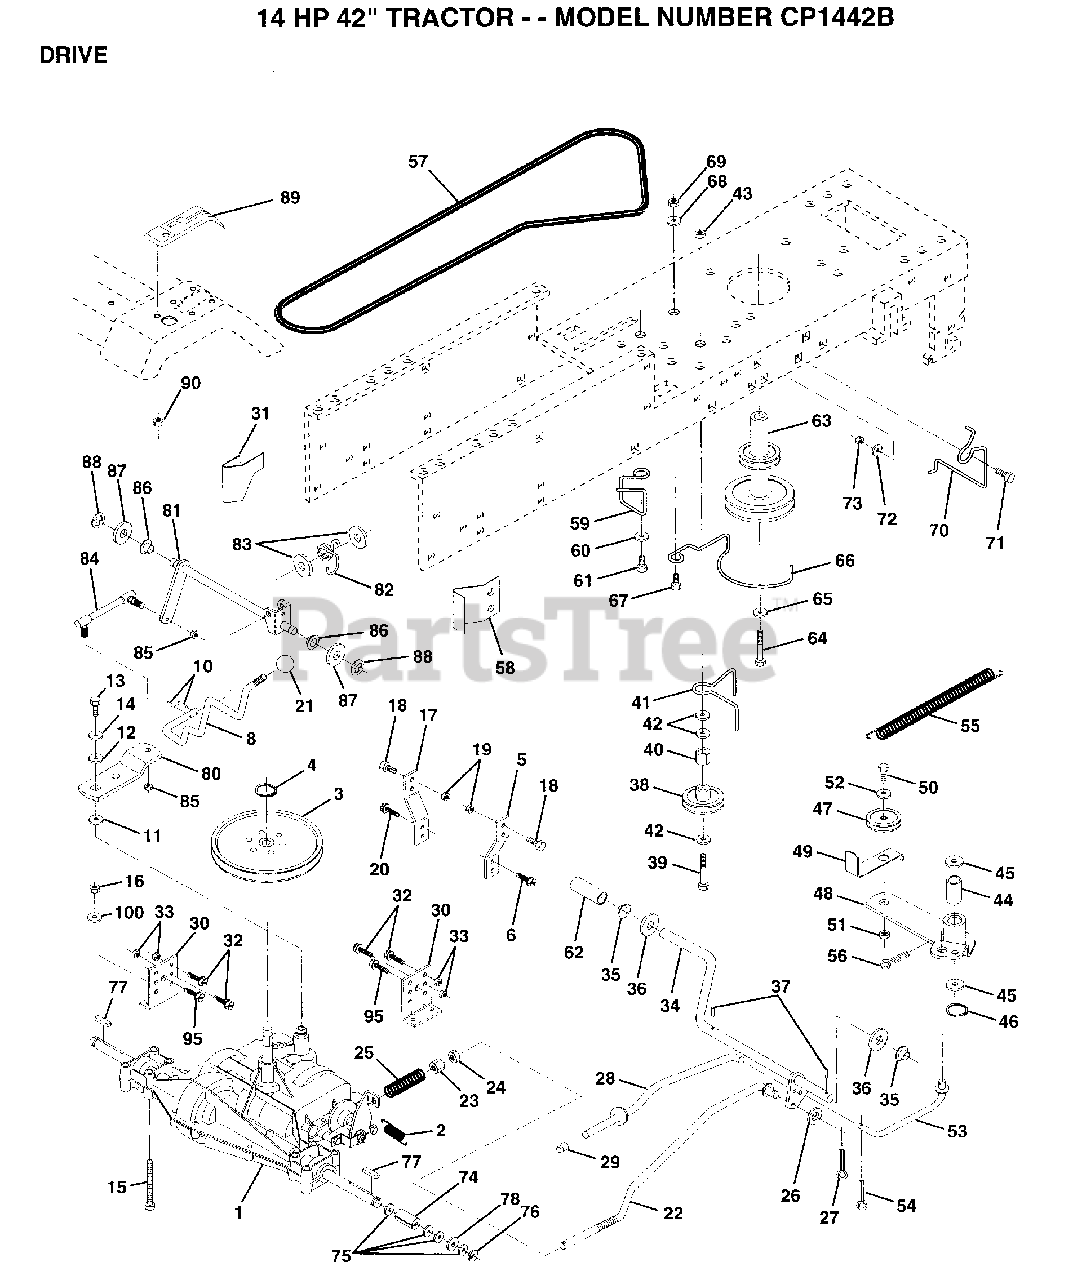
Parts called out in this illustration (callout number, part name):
3	PULLEY TRANS
5	STRAP TORQUE
6	SCREW
8	ROD SHIFT FEND LT
10	PIN COTTER 1/8
11	WASH-SHFT PLT LT
12	WASHER
14	LOCKWASHER
15	BOLT HEX
16	NUT
17	STRAP TORQUE
18	BOLT
19	NUT
20	SCREW
21	KNOB T (1/2-HOLE)
22	BRAKE ROD
23	NUT
24	NUT
25	SPRING ROD LT
26	WASHER
27	COTTER PIN
28	ROD PARK BRAKE
29	PLUNGER CAP T
30	TRANSAXLE MTG BKT
31	"KEEPER,BELT LH T"
32	BOLT
33	NUT
35	NYLON BEARING
36	WASHER LT
38	PULLEY.IDLER.FLAT
39	BOLT
40	SPACER T
41	BELT KEEPER LT
42	WASHER
43	NUT
44	"LY, BEARING"
45	WASHER LT
46	KLIP RING
48	ARM IDLER
49	RETAIN BELT
52	WASHER
53	"LINK, CLUTCH T"
54	COTTER PIN
55	"SPRING, RETURN LT"
56	COTTER PIN
58	"KEEPER,BELT RH T"
59	KEEPER BELT CNTSP
60	WASHER
61	SCREW
62	PEDAL COVER T
63	PULLEY.ENGINE
64	BOLT
65	LOCKWASHER
66	KEEPER.BELT.ENG.L
67	BOLT
68	WASHER
70	KEEPER BELT ENG
71	BOLT
72	WASHER
74	SPACER LT
75	WASHER
76	E-RING LT
77	SQUARE KEY
78	WASHER
80	ARM SHIFT TRANS
81	SHAFT ASM.SHIFT
82	"SPRING,TORSION"
83	WASHER
84	TIE ROD
85	NUT 1/4-28
86	BUSHING
87	WASHER D
88	KLIP RING
90	NUT
95	SCREW
100	WASHER M
